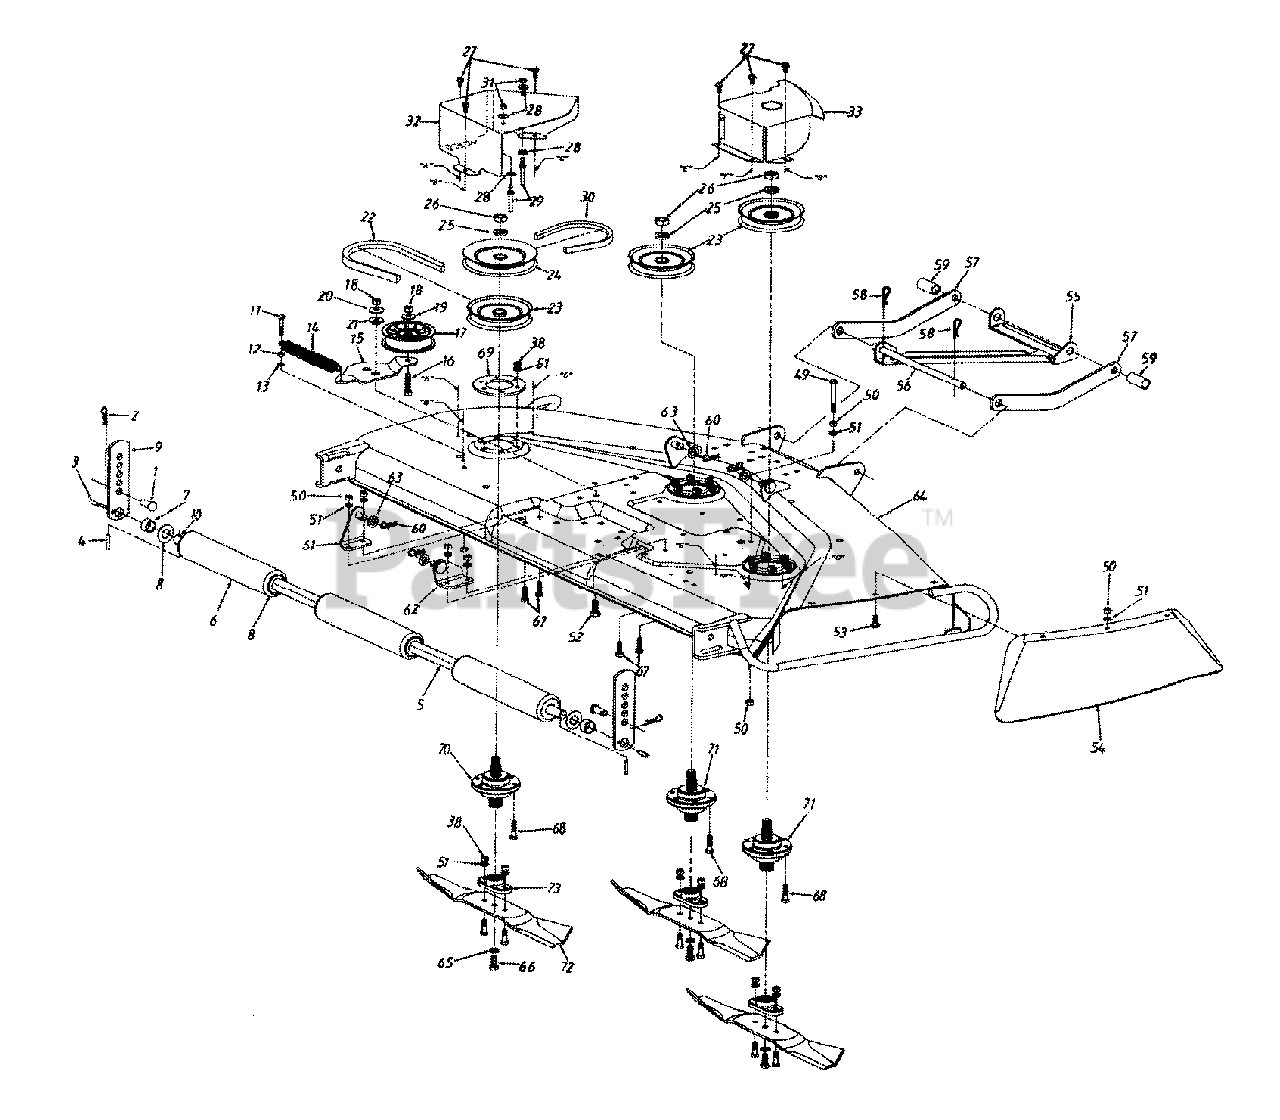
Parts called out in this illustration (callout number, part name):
2	Hairpin Clip
3	Spring Pin 1/4" x 1" Lg.
4	Spring Pin 3/16" x 1-1/4" Lg.
7	Spacer .75" I.D.
8	Fl-Wash. .76" I.D. x 1.5" O D.
10	Roller Shaft
11	Hex Bolt 1/4-28 x 1.5" Lg. (Gr. 5)
12	Hex Nut 1/4-28 Thd.
13	L-Wash. 1/4" I.D.
14	Ext. Spring 7.33" Lg.
17	Idler Pulley
18	Hex Nut 3/8-24 Thd.
19	Bell-Wash. 3/8" I.D.
20	Bell-Wash. .39" I.D. x 1.13" O.D.
21	Shld. Spacer .625" I.D.
22	"V"-Belt
24	Upper Deck Pulley
25	L-Wash. 5/8" I.D.
26	Hex Jam Nut 5/8-18 Thd.
27	Hex Wash. Hd. Scr. 1/4-20 x .5" Lg.
28	Bell-Wash. 1/4" I.D.
29	Belt Guard Pin
30	"V"-Belt
31	Hex Nut 1/4-20 Thd.
49	Hex Bolt 5/16-18 x 2.5" Lg.
50	Hex Nut 5/16-18 Thd.
51	L-Wash. 5/16" I.D.
52	Hex Bolt 3/8-24 x 1" Lg.
53	Carr. Bolt 5/16-18 x .75" Lg.
59	Spacer 1.75" Lg.
60	Hairpin Clip
61	Deck Hanger Brkt. - L.H.
62	Deck Hanger Brkt. - R.H.
63	Fl-Wash. 1/2" I.D. x .93" O.D.
66	Hex Bolt 3/8-24 x .88" Lg. (Gr. 5)
67	Hex Bolt 5/16-18 x 1" Lg.
68	Hex Bolt 5/16-24 x 1-1/4" Lg. (Gr. 5)
69	Spindle Reinforcement Plate
70	Spindle Ass'y. (L.H.)
71	Spindle Ass'y. (R.H. & Center)
72	Blade
73	Blade Adapter
